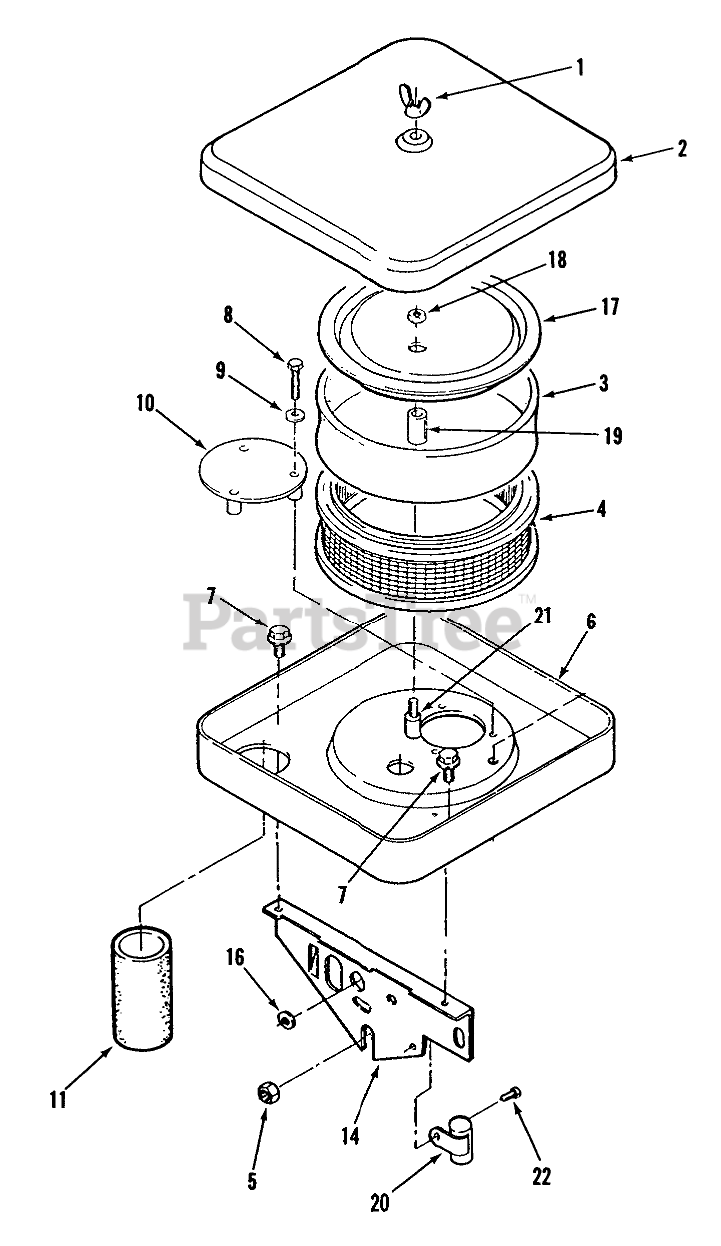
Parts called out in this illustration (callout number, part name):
1	Nut-Wing
2	CHROME-AIR CLEANER
3	AIR CLEANER ELEMENT
4	Air Cleaner Element
5	Nut
6	Air Cleaner Housing
7	Screw 1/4-20 x 3/8
8	Screw Hex Hd. #10-32 x 1-1/2
9	Flat Washer #10
10	AIR DEFLECTOR PLATE
11	AIR INTAKE TUBE
14	AIR CLEANER SUPPORT
16	Grommet
17	Element Cover
18	Hex Nut 1/4-20
19	Spacer
20	Condenser
22	SCREW #10-32 X 5/8
